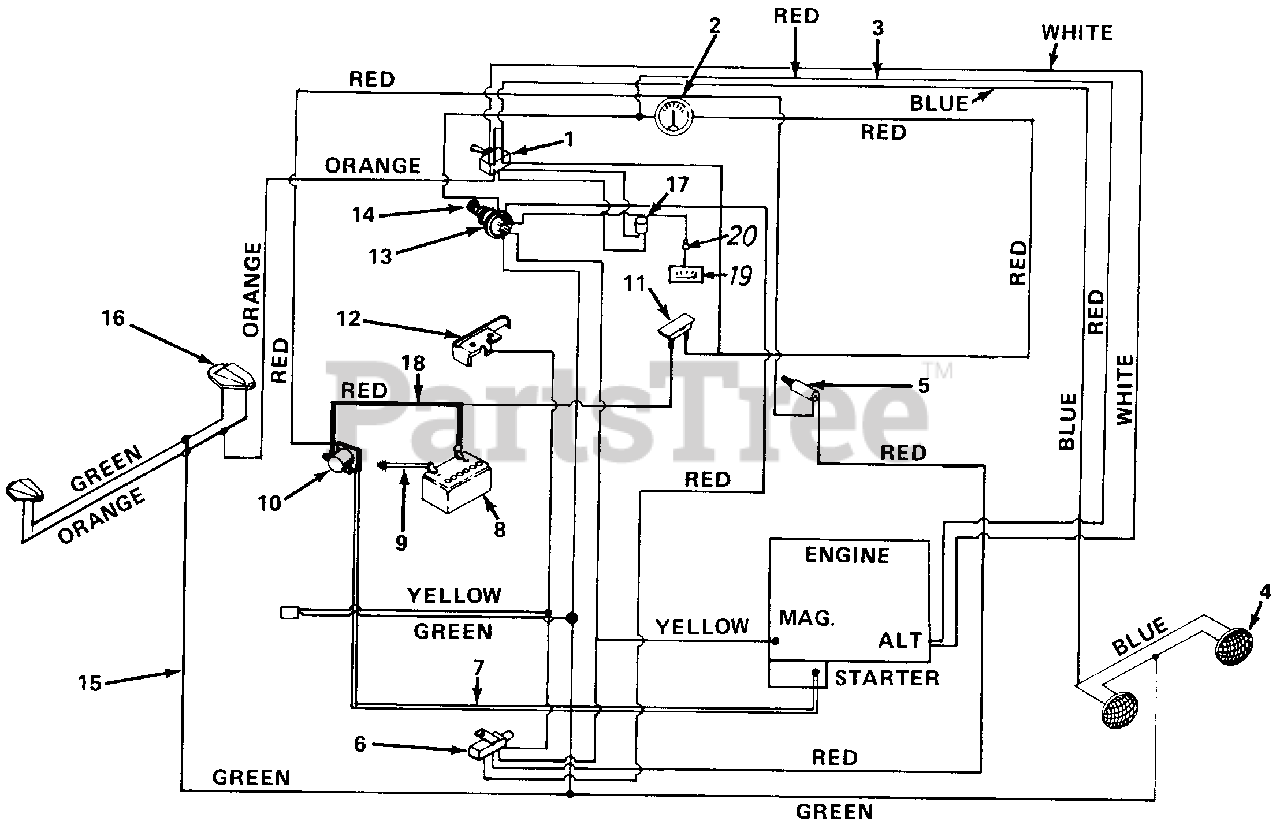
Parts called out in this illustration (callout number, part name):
1	Light Switch
2	Ammeter
3	Wire Harness
4	Headlight
5	Safety Switch Clutch
6	Safety Switch PTO
7	Electric Wire
8	Battery 12 V.
9	Electric Wire
10	Solenoid
11	Circuit Breaker
12	Spring Switch
13	Ignition Switch
14	Ignition Key
15	Tail Light Lead
16	Tail Light
18	Electric Wire
20	Hour Meter Lead
